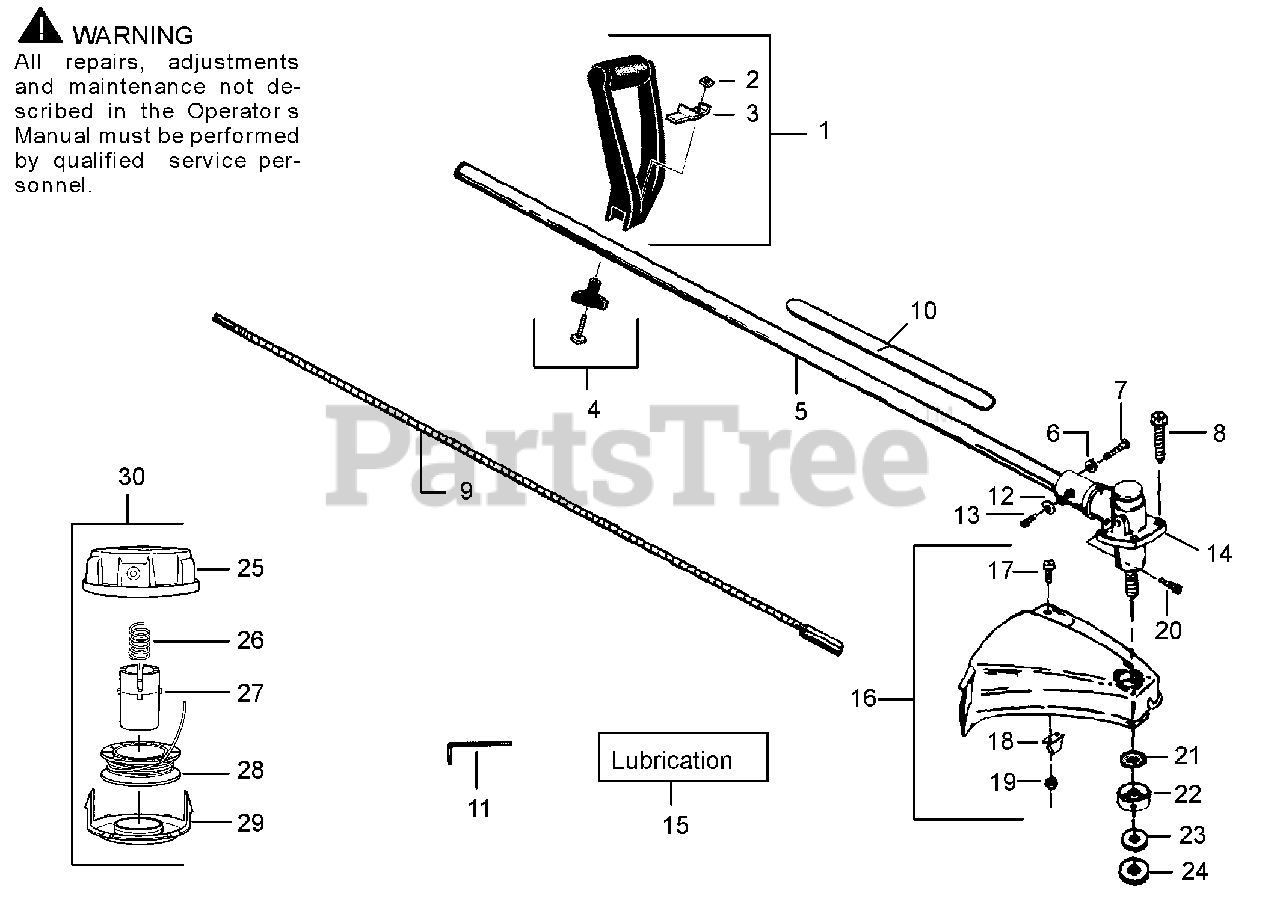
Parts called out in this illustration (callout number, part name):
1	Assist Handle Kit
4	"T" Handle Ass'y.
5	Drive Shaft Housing
6	Lockwasher
9	Drive Shaft
10	Shaft Warning Decal
11	Hex Wrench (5/32)
12	Lockwasher
14	Gear Box Assy.
15	Shaft Lubrication
16	Shield Kit Assy.
18	Line Limiter
19	Locknut
22	Dust Cup
23	Grass Washer
25	Hub Assy.
27	Release Button
28	Spool w/Line
30	Cutting Head Ass'y
